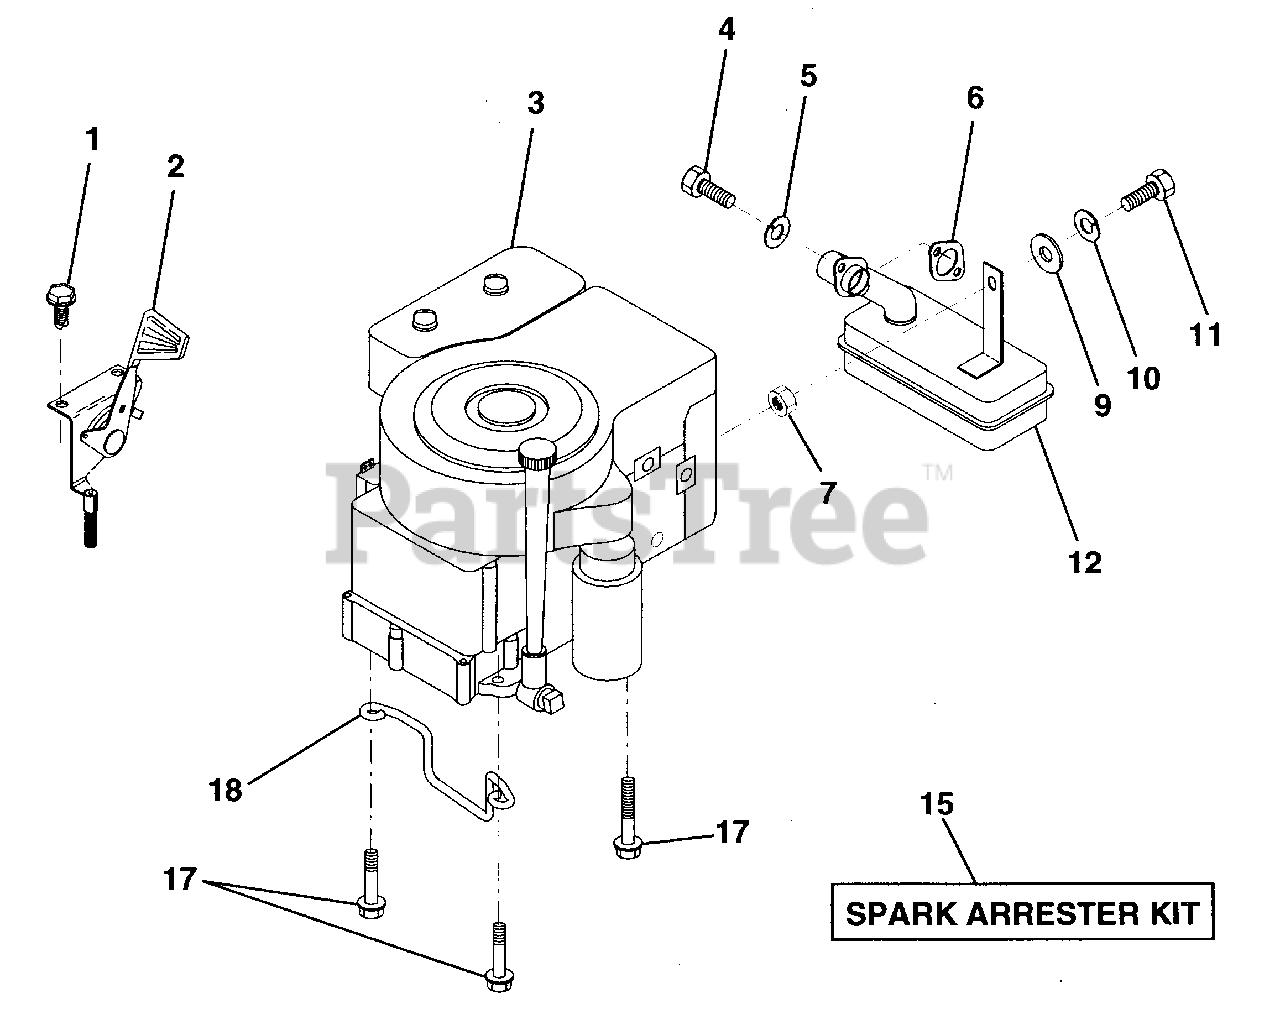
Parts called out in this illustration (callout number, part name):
1	Screw, Hex Head, Thread-Cutting 1/4-20 x 1/2
2	Control, Throttle
4	Screw, Hex Cap Head 5/16-18 x 3/4
5	Washer, Lock, Heavy Helical Spring 5/16
6	Gasket, Exhaust
7	Nut Fin H 5/16 - 18
9	Washer 5/16 x 3/4 x 16 Gauge
10	Washer, Lock, Heavy Helical Spring 1/4
11	Bolt, Hex, Fin. 1/4-20 UNC x 1
15	Arrester, Spark
17	Screw, Hex Washer Head, Thd., Roll. 3/8-16 x 1-1/2
18	Keeper, Ground Drive Belt
